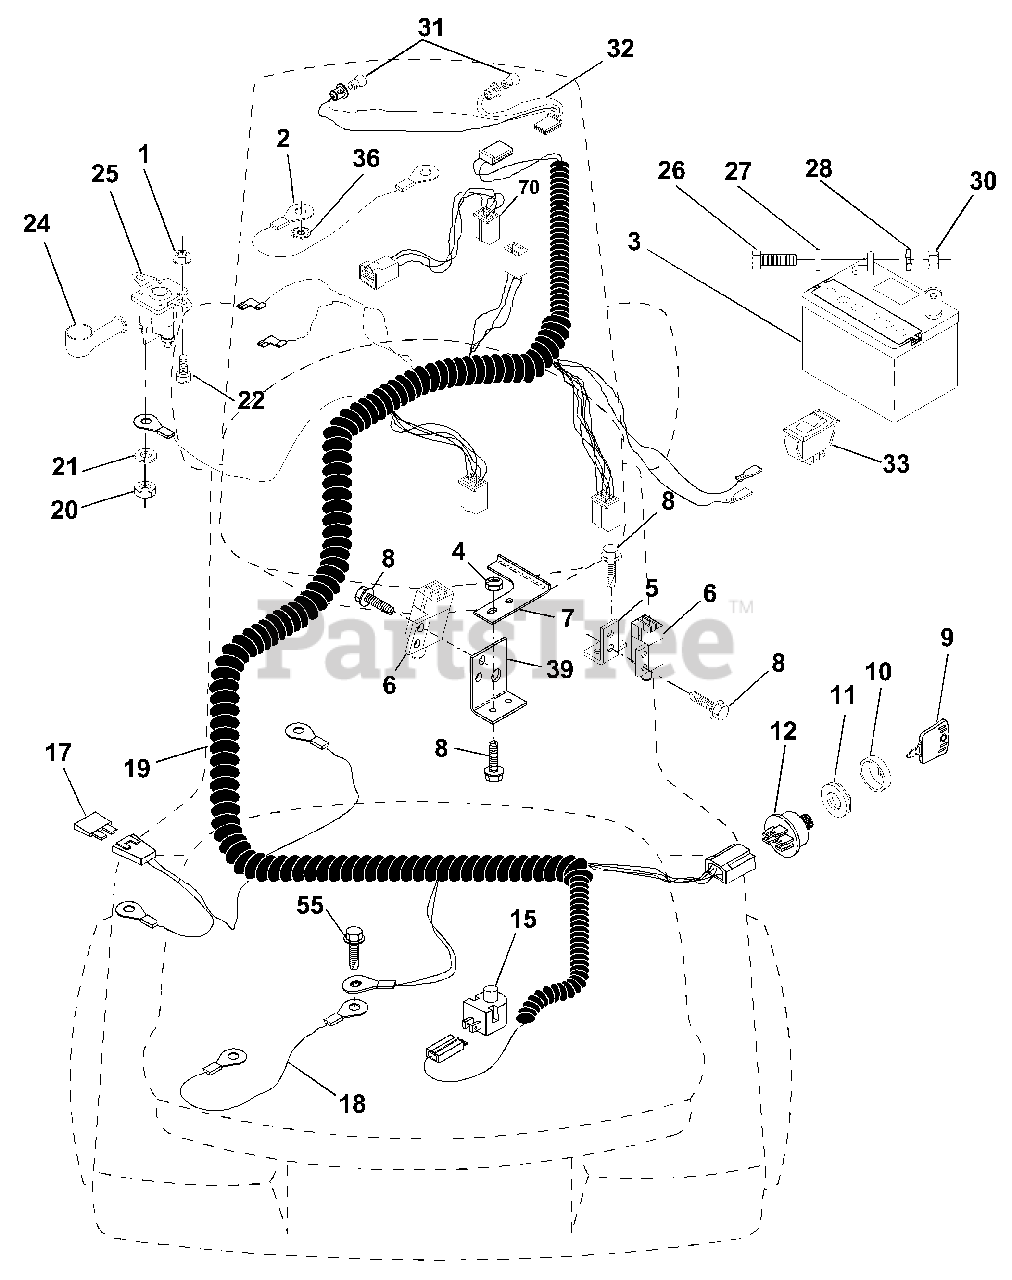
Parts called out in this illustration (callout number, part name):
1	Nut, Hex, Keps 1/4-20
2	Assembly, Cable
3	Battery
4	Nut, Lock #10-24 Unc
5	Bracket, Switch
6	Switch, Interlock, 4 Terminal
7	Keeper, Actuator
8	Screw, Hex Head, Self-Tapping #10-24 x 1/2
9	Key, Molded
10	Cover, Ignition Key
11	Nut, Ignition
12	Switch, Ignition
15	Switch, Plunger
18	Assembly, Cable
19	Harness, Ignition
20	Nut, Hex, Jam 1/4-20
21	Washer, Lock 1/4
22	Bolt, Hex, Fin. 1/4-20 UNC x 1/2 Grade 5
24	Cover, Terminal
25	Solenoid
26	Bolt, Hex Head 1/4-20 UNC x 3/4
27	Washer 9/32 x 5/8 x 16 Gauge
28	Washer, Lock 1/4
30	Nut, Hex, Fin. 1/4-20 UNC
31	Bulb, Light
32	Harness, Headlight
33	Switch, Light
36	Washer, Lock, Internal Tooth 1/4
39	Bracket Switch Clutch
55	Screw Thdrol 5/16 -18 x 1/2
70	Harness, Engine
